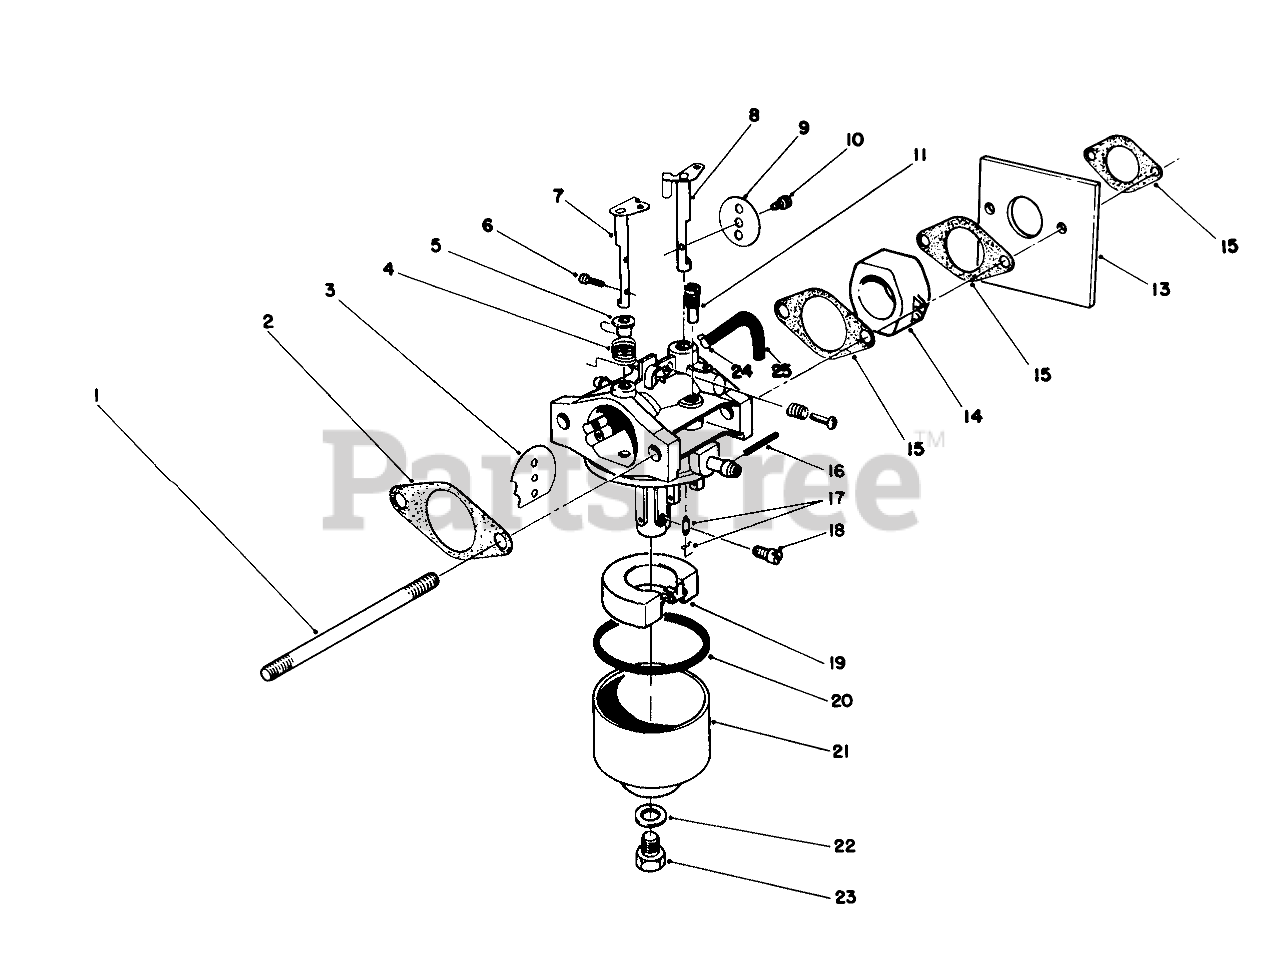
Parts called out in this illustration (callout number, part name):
1	STUD-CARBURETOR
1	GASKET
2	GASKET-AIR CLEANER
2	Arrestor-Spark
3	PLATE
3	Clamp
4	SPRING
4	Muffler
5	BUSHING
5	COVER-MUFFLER
6	SCREW
7	SHAFT-CHOKE
7	WASHER-LOCK
8	SHAFT
9	PLATE
10	Screw-Throttle
10	SCREW
11	PILOT JET
13	SHIELD-CARBURETOR
14	INSULATOR-CARBURETOR
15	GASKET-CARB
16	Pin
17	NEEDLE
18	JET-MAIN
19	FLOAT
20	GASKET
21	BOWL - FLOAT
22	Gasket-Bowl Screw
23	SCREW
24	CLAMP
25	VENT TUBE
